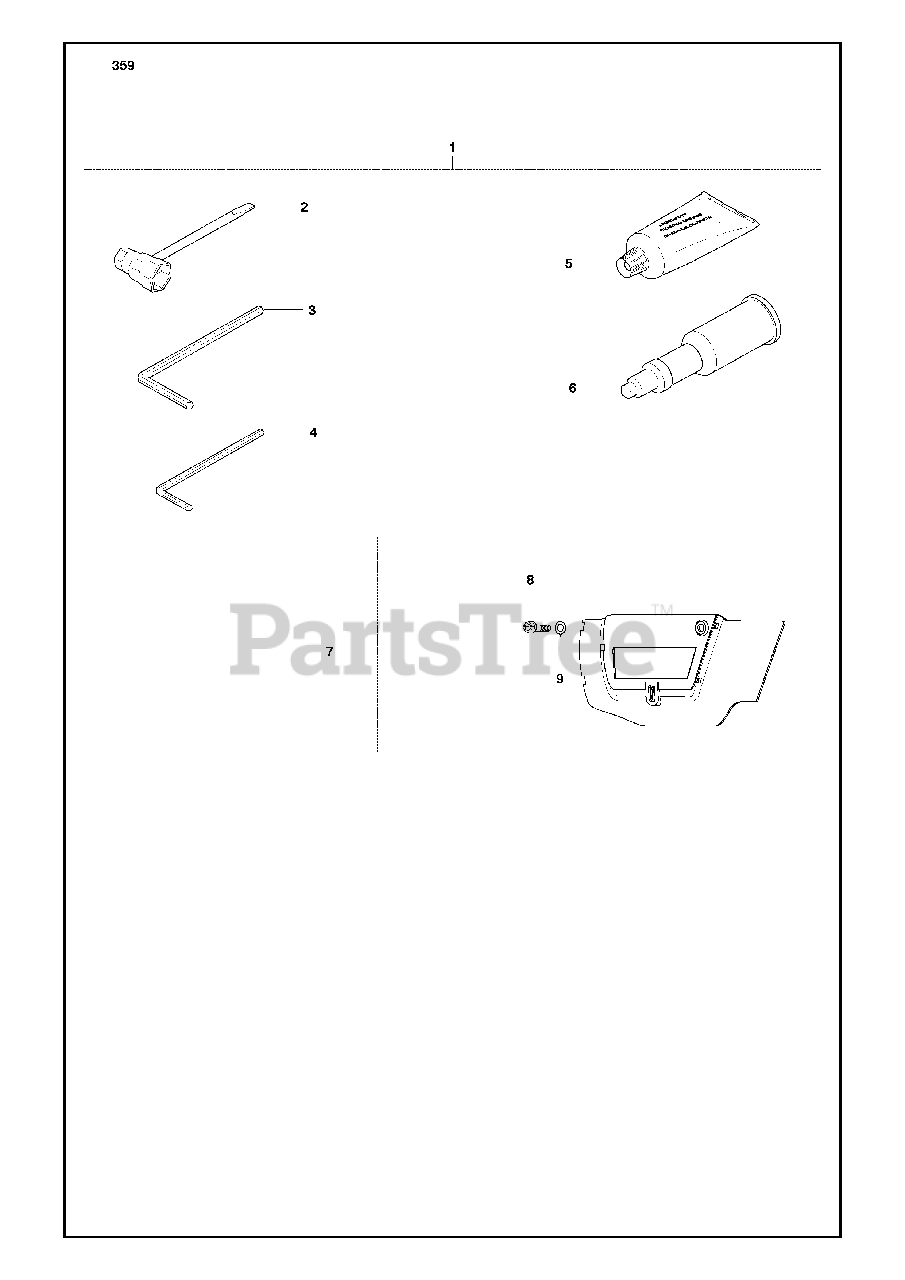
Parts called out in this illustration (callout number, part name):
1	TOOL KIT
2	COMBI TOOL
5	GREASE
6	Grease Gun
7	PROTECTOR
